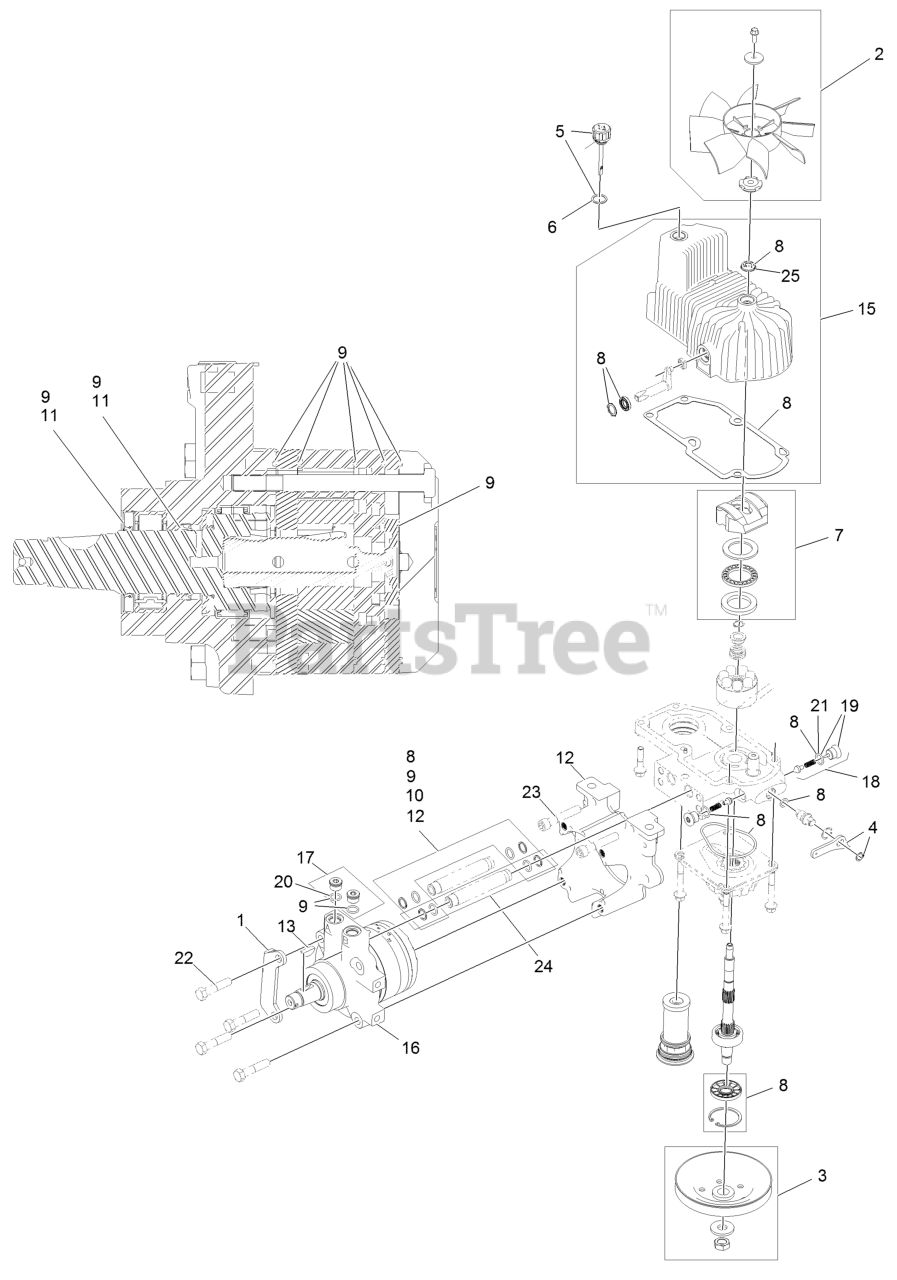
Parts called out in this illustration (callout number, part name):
1	MOUNT-SHOE, HORSE
2	FAN KIT
3	PULLEY KIT
4	HANDLE-BYPASS VALVE, HYDRO
5	DIPSTICK-HYDRO W/GASKET
6	GASKET-DIPSTICK, HYDRO
7	SWASH BLOCK KIT
8	PUMP SEAL KIT
9	MOTOR SEAL KIT
10	TUBE SEAL KIT
11	OUTPUT SHAFT SEAL KIT
12	NOSE CUP-UHT
13	KEY-WOODRUFF
15	HOUSING-HYDRO, RH
16	MOTOR-HYDRAULIC RH 240CC
17	MAGNETIC PLUGS SERVICE KIT
18	CHECK VALVE ASM
19	PLUG-CHECK (W/O-RING)
21	O-RING-CHECK VALVE
22	SCREW HH
23	SCREW-HSH
24	HYDRAULIC TUBE KIT
25	SEAL-FAN DRIVE
